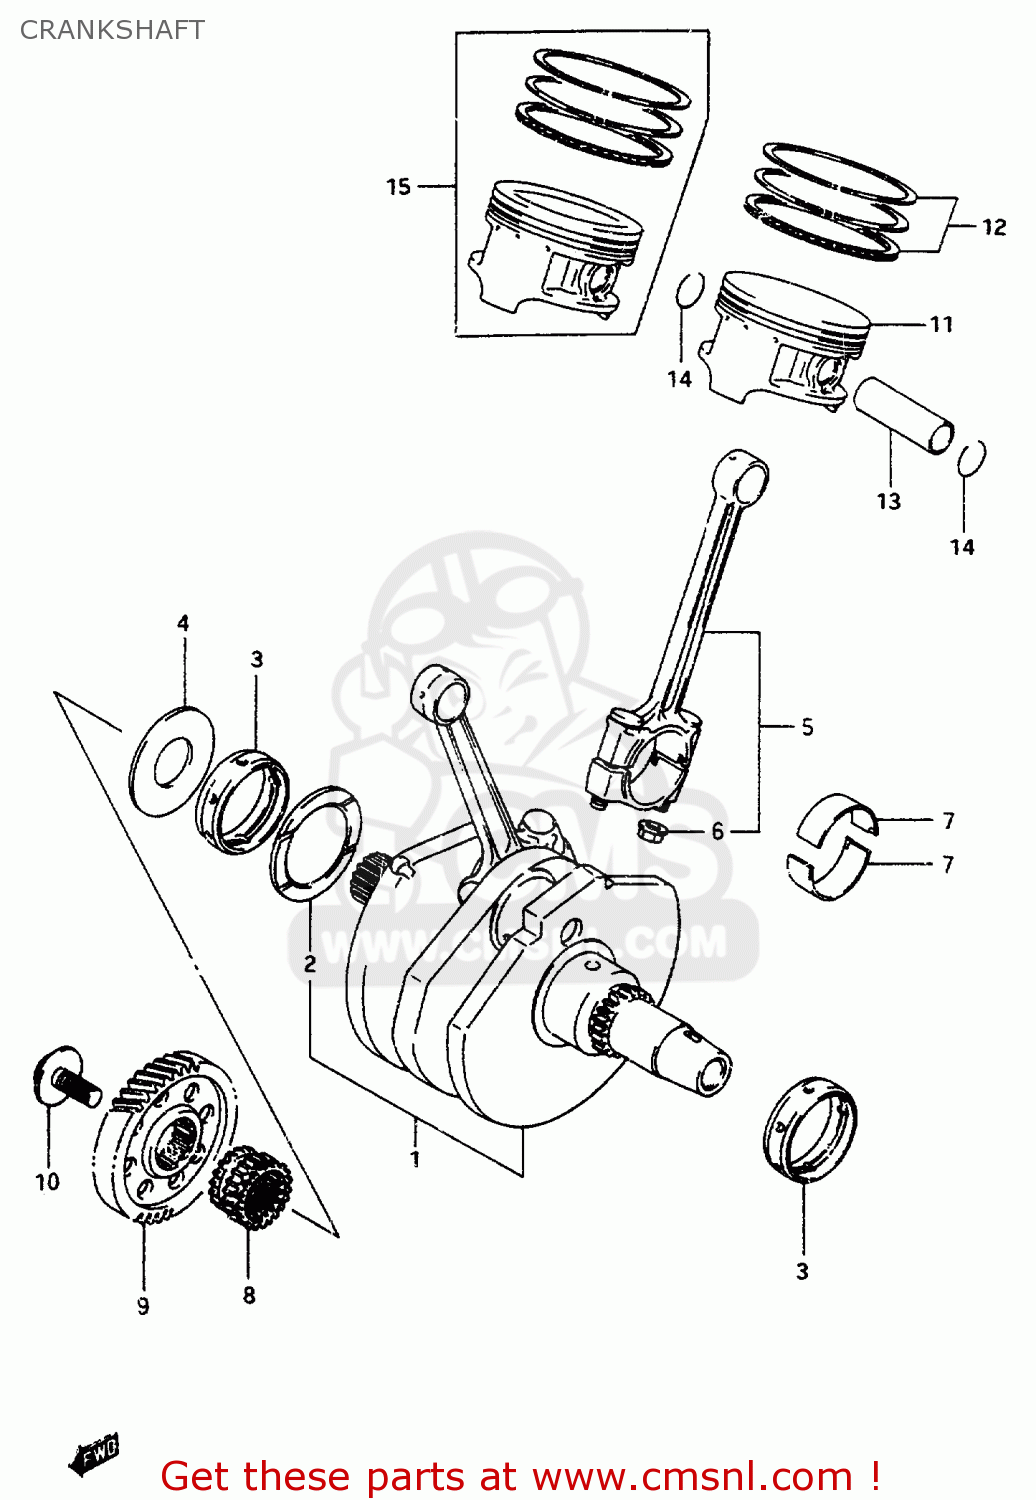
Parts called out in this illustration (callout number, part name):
1	CRANKSHAFT SET
2	WASHER(48.1X64X1.94)
3	METAL,CRANKSHAFT
4	WASHER,CRANK THRUST
5	CONNECTING ROD ASSY
6	NUT
7	BEARING,CRANK PIN
8	SPROCKET,CAM CHAIN DRIVE,R
9	GEAR,PRIMARY DRIVE
10	BOLT(12X28)
11	PISTON
12	RING SET,PISTON
13	PIN,PISTON
14	CIRCLIP,PISTON PIN
15	PISTON SET(OS:0.5)
